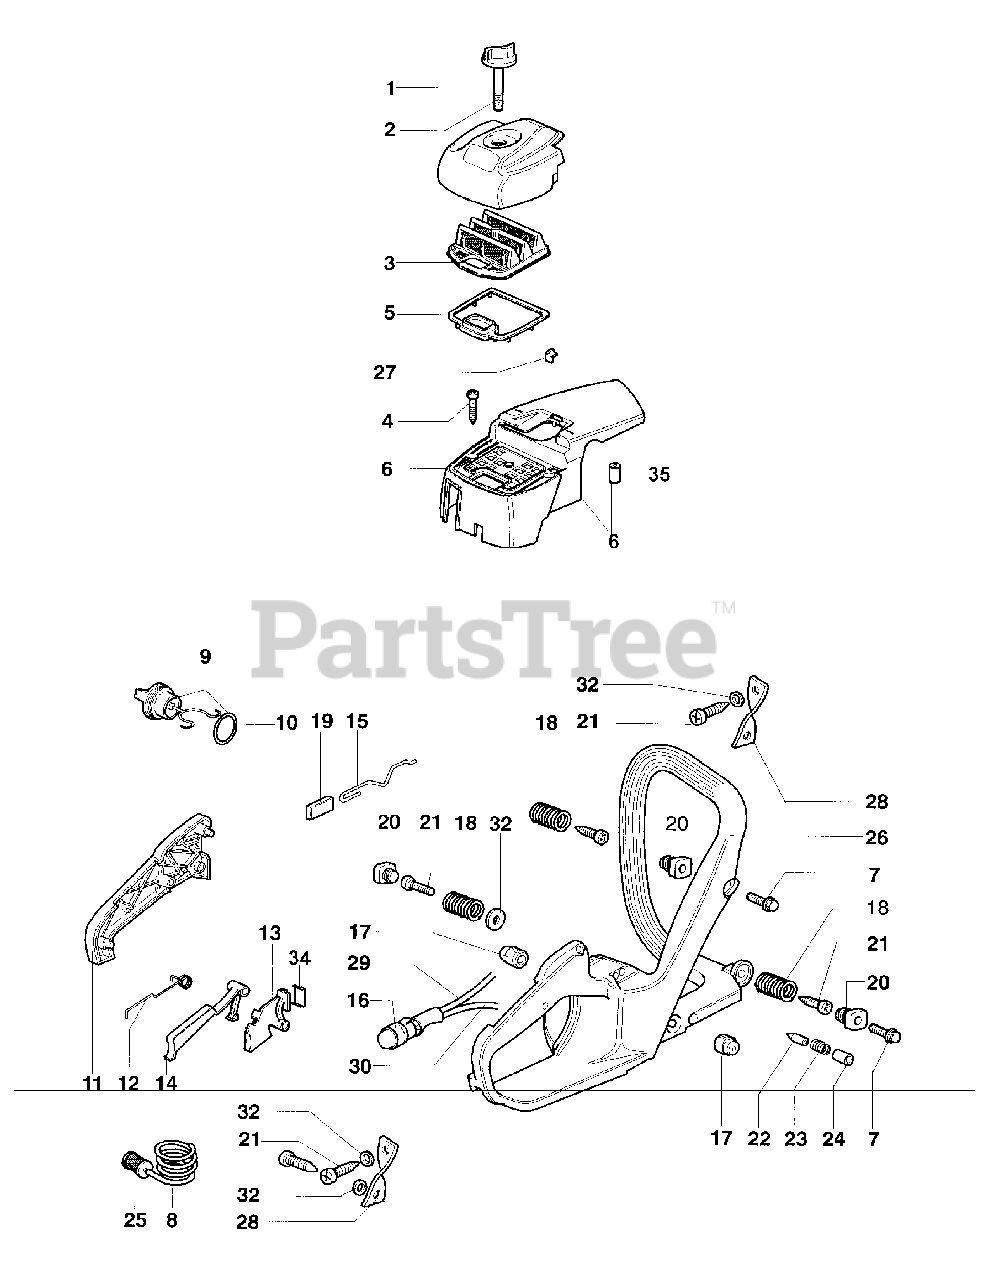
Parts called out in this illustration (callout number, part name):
2	FILTER COVER
12	SPRING
13	THROTTLE LEVER
14	THROT. INTERLOCK
15	THROTTLE ROD
17	SHOCK ABSORBER
19	ROD CAP
22	TANKBREATHER
24	TANKBREATHER
26	COMPL. FUEL TANK
